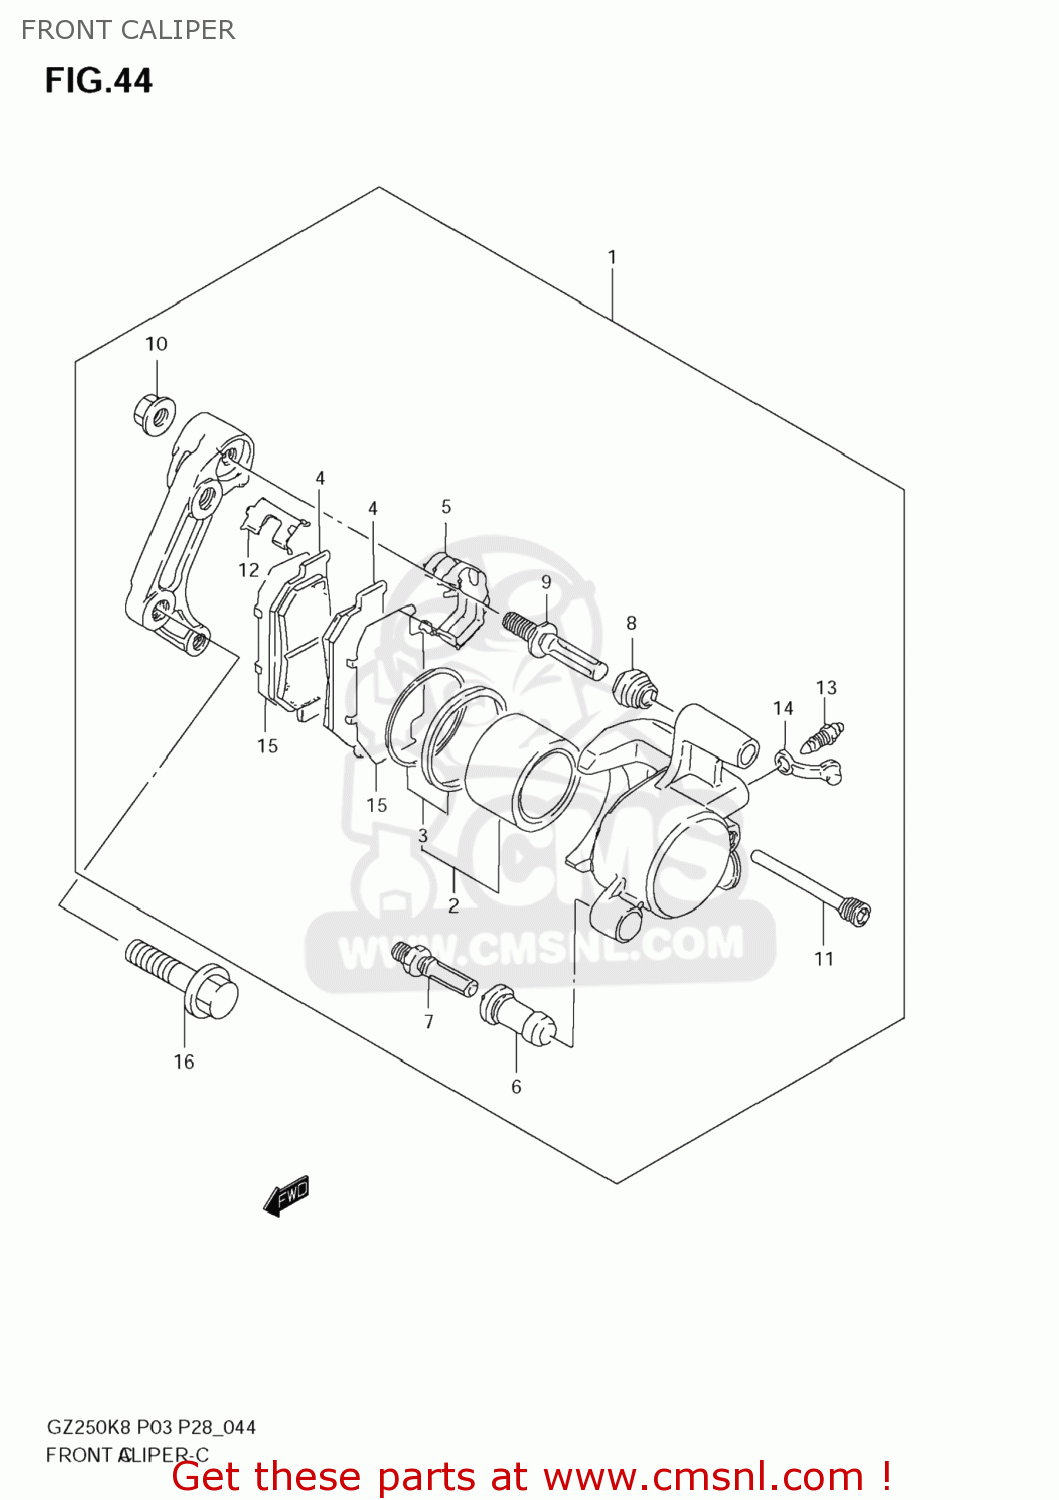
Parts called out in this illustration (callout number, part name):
1	CALIPER ASSY, G
2	PISTON SET
3	.SEAL SET, PISTON
4	BRAKEPADSET
5	SPRING
6	BOOT
7	PIN
8	BOOT
9	BOLT
10	NUT
11	PIN
12	RETAINER
13	BLEEDER
14	CAP
15	SHIM
16	BOLT
